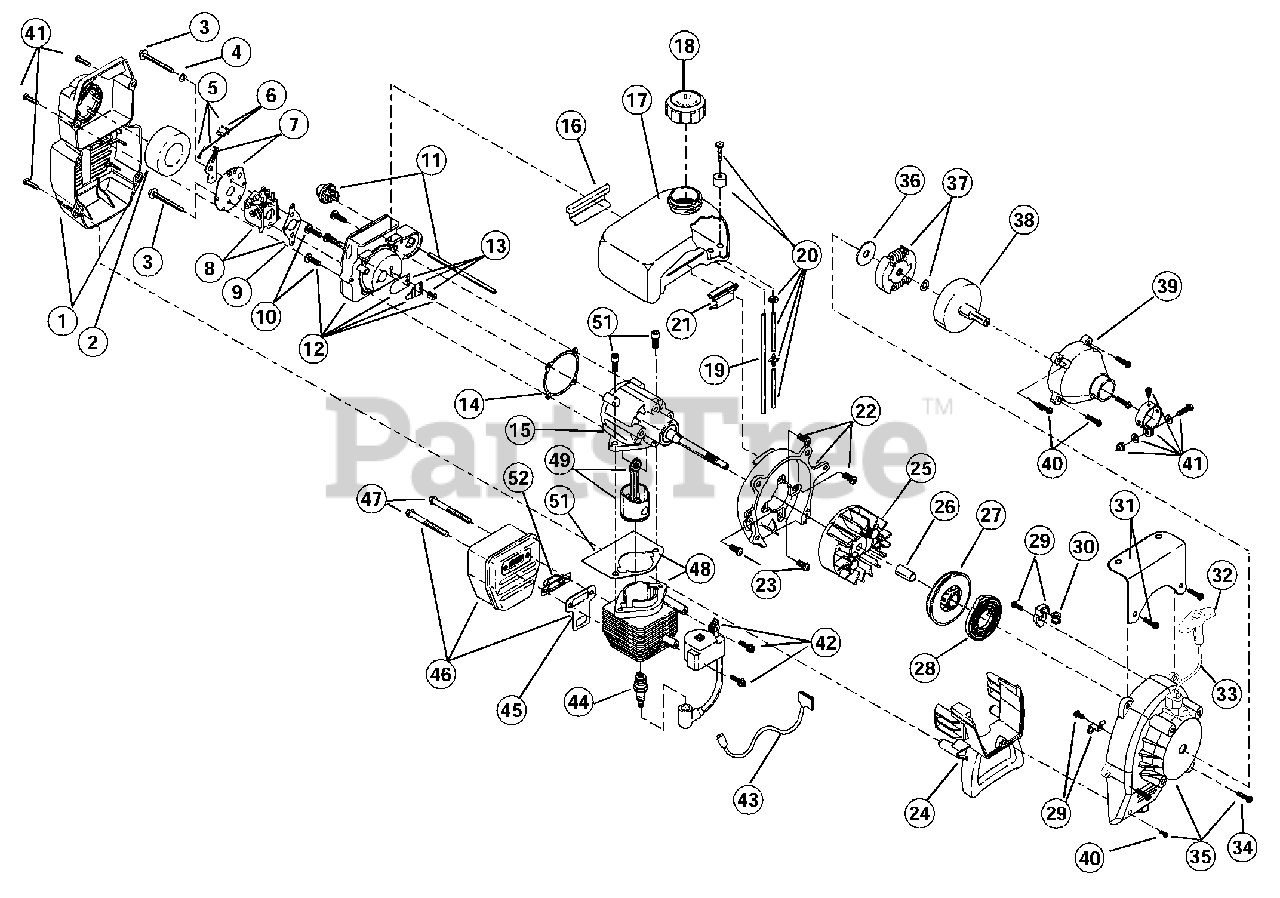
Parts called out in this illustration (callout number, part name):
1	Air Cleaner/Muffler Cover Assembly
2	Air Cleaner Filter
3	Carburetor Mounting Screw Assembly
4	Wavey Washer
5	Choke Lever Assembly
6	Choke Knob and Screw
7	Choke Lever and Plate
8	Carburetor Assembly
9	Carburetor Gasket
10	Carb Mount Screw
11	Primer and Hose Assembly
12	Carb Mount Assembly
13	Reed Assembly
14	Carburetor Mount Gasket
15	Crank Case Service Assembly
16	Rear Mounting Pad
17	Fuel Tank Assembly
18	Fuel Cap Assembly
19	Fuel Return Line
20	Fuel Line Assembly
21	Front Mounting Pad
22	Shroud Assembly
23	Shroud Screw
24	Shroud Extension and Stand
25	Flywheel Assembly
27	Recoil Pulley Assembly
28	Recoil Spring
29	Pulley Retainer Assembly
30	Rope Guide
31	Fuel Tank Guard Assembly
32	Pull Handle
34	Housing Screw
35	Starter Housing Assembly
36	Clutch Washer
37	Clutch Rotor Assembly
38	Clutch Drum Assembly
39	Clutch Cover Assembly
40	Cover Screw
41	Upper Clamp Assembly
42	Module Assembly
43	Wire Lead
44	Spark Plug
45	Exhaust Gasket
46	Muffler Assembly
47	Muffler Mounting Bolt
48	Cylinder Assembly
49	Piston and Rod Assembly
50	Cylinder Gasket
51	Cylinder Bolt
52	Spark Arrestor
